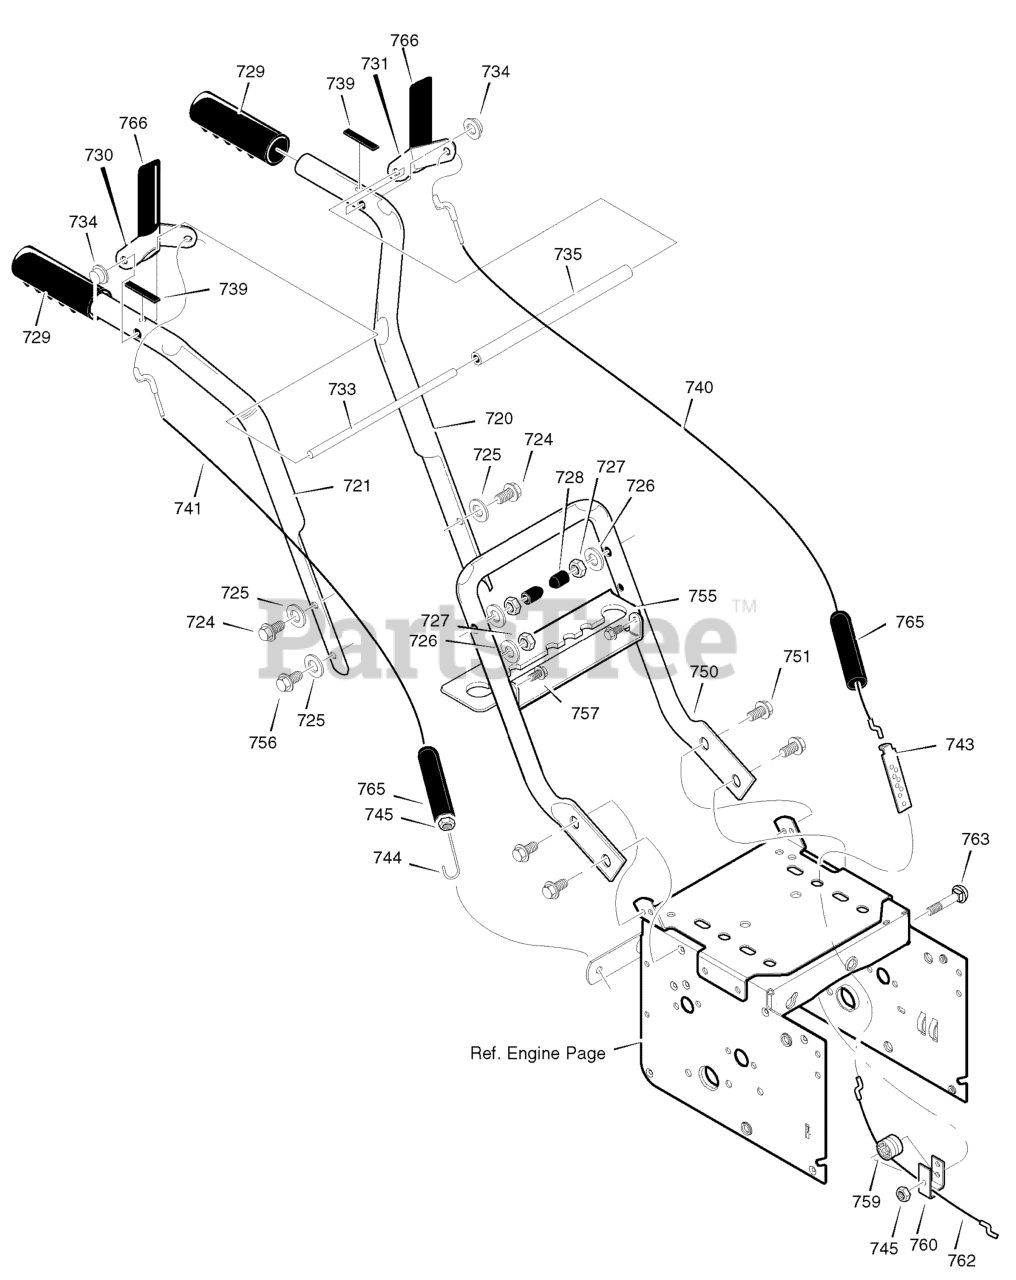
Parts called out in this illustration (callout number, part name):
720	HANDLE, UPPER LH
721	HANDLE, UPPER RH
724	SCREW, 5/16-18 X 2.75
725	WASHER, FLAT
726	WASHER, SPTLK .31X.58X.08
727	NUT, 5/16-18
728	STOP, RED PLASTIC
729	GRIP-HANDLE FINGER
730	LEVER, ASSY CLUTCH DRIVE RH
731	LEVER, ASSY CLUTCH DRIVE LH
733	ROD, PIVOT CLUTCH
734	NUT, PUSH ON CAP
735	SPACER-HANDLE
739	BUMPER, RECTANGLE
740	CABLE, CLUTCH 28.44L
741	CABLE, AUGER CLUTCH
743	BRACKET, CABLE ADJUSTER
744	SPRING, AUGER CLUTCH
745	NUT, 1/4-20
750	HANDLE, LOWER
751	SCREW 5/16-18 X .75
755	BRKT, GEAR SELECTOR
756	SCREW, 5/16-18 X 2.00
757	SCREW, 1/4-20 X 0.63
759	SPOOL-CABLE, AUGRT CLUTCH
760	BRACKET, CABLE SPOOL YZ
762	CABLE, LOWER DRIVE 12"
763	BOLT, HEX 1/4-20 X 1.75 YZ
765	BOOT, CLUTCH SPRING
766	GRIP
